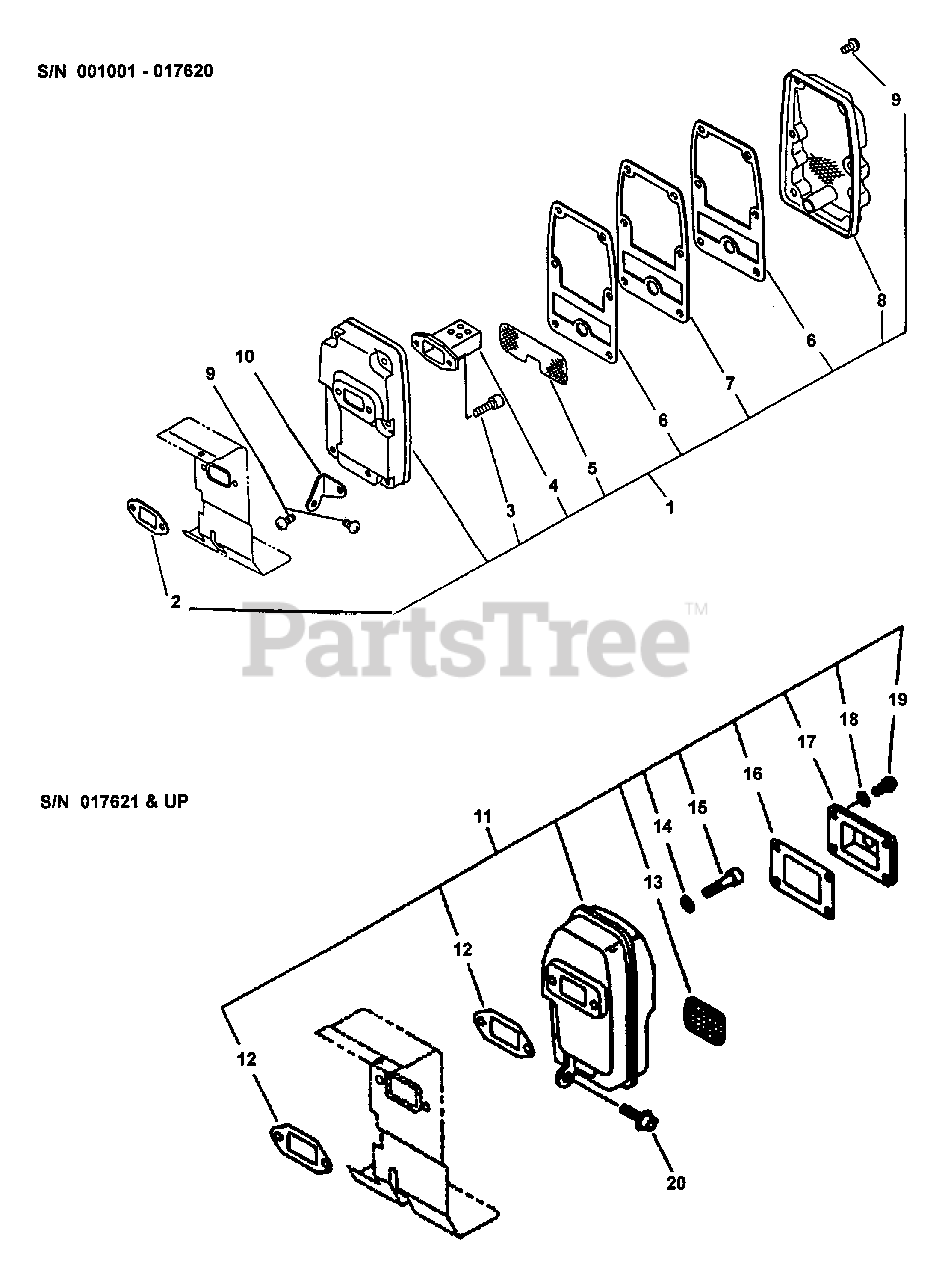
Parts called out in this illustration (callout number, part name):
1	MUFFLER ASSY
2	GASKET, EXHAUST
3	SCREW - 5X18
4	BAFFLE, MUFFLER
5	SCREEN, SPARK ARRESTOR
6	GASKET, EXHAUST
7	GASKET, EXHAUST
8	LID, MUFFLER
9	SCREW - 5X16
10	STAY, MUFFLER
11	MUFFLER ASSY
12	GASKET, EXHAUST
13	SCREEN, SPARK ARRESTOR
14	WASHER - 5
15	SCREW - 5X60
16	GASKET, EXHAUST
17	GUIDE, EXHAUST
18	LOCKWASHER - 4
19	SCREW - 4X12
20	SCREW - 5X16
